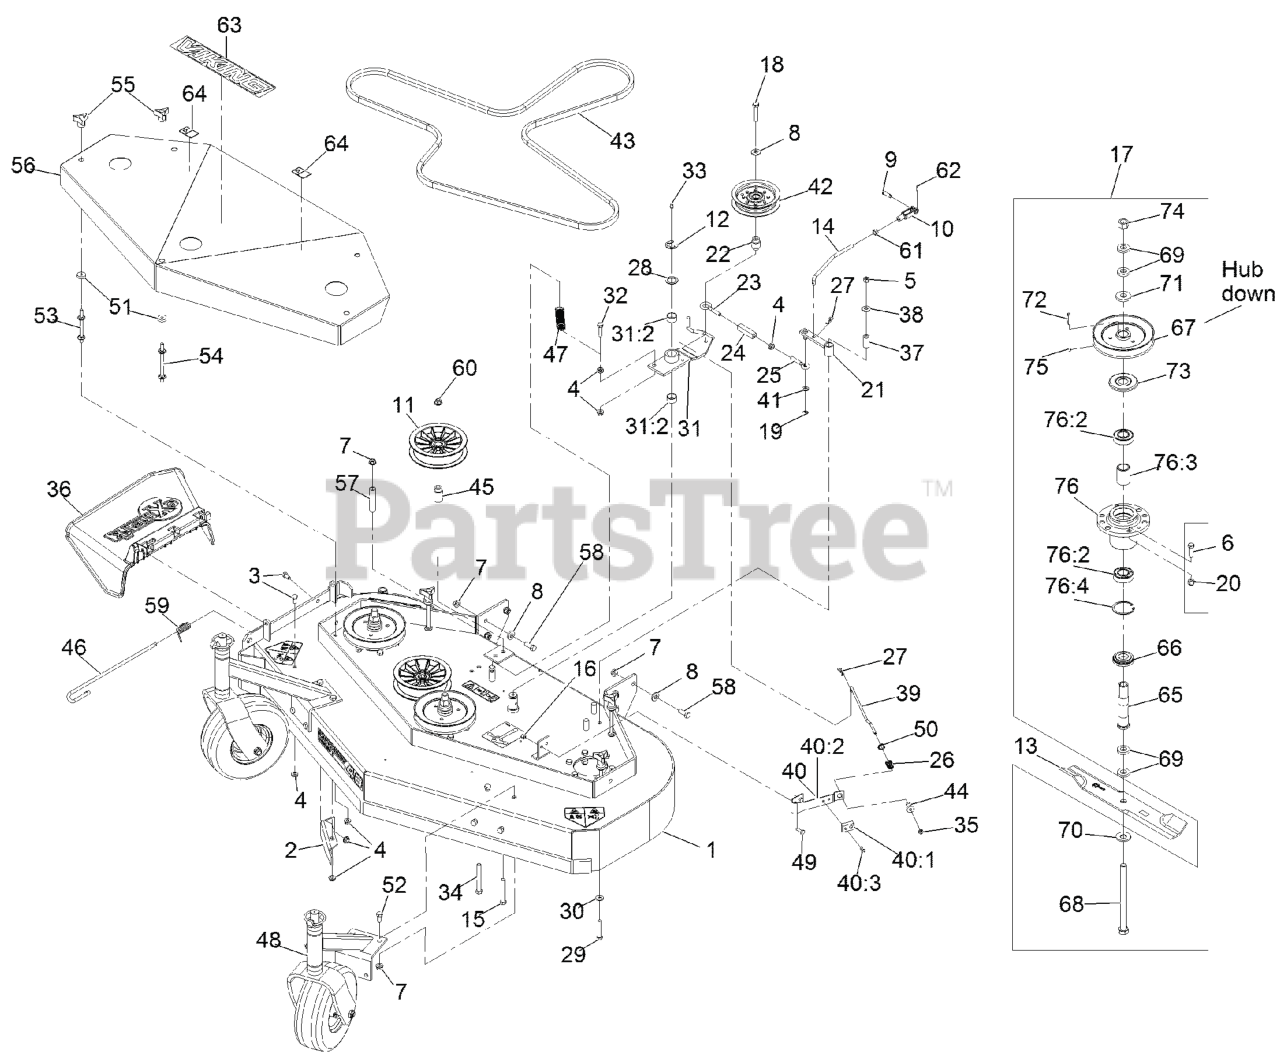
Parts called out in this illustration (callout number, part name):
1	DECK-SERVICE, 48
2	BAFFLE-DOGLEG
3	SCREW-HH
5	NUT-LOCK, NI
6	SCREW-HH
7	NUT-HHF, WHIZ
8	WASHER-BELLEVILLE
9	PIN-CLEVIS
10	YOKE-ADJUSTABLE
11	PULLEY,IDLER 5"
12	RING-RETAINING, EXT
14	ARM-LINKAGE, ASSIST
15	SCREW-HH
16	NUT-LOCK, NI
17	ASM, CUTTER HOUSING OUTER
18	SCREW-HH
19	RING-RETAINING, EXT
20	NUT-LOCK, NI
21	ARM-ASSIST, 32/36
22	BUSHING-ENGAGEMENT
23	EYEBOLT-THREAD, LH
24	BODY-TURNBUCKLE
25	EYEBOLT-THREAD, RH
26	SPRING-COMPRESSION
27	PIN-COTTER
28	WASHER-SPINDLE
29	SCREW-HH
30	WASHER-SPRING
31	IDLER ARM ASM
31:2	SLEEVE-BEARING
32	SCREW-HH, SPECIAL
33	FITTING-GREASE
34	SCREW-HH
35	NUT-LOCK, NI
36	CHUTE DEFLECTOR XRK M056
37	TUBE-PIVOT
38	WASHER-FLAT
39	ROD-BRAKE
40	PAD AND SPRING ASM
41	WASHER-PLAIN
43	BELT,BLADE 48
44	SPACER-FLANGED
45	BUSHING-IDLER
46	PIN-CHUTE
47	SPRING-EXTENSION
48	ASM-CASTER MNT W/WEIGHT
49	SCREW-HH
50	RING-PUSH ON
52	SCREW-HH
53	STUD-SHIELD, BELT (SHORT)
54	STUD-SHIELD, BELT (LONG)
55	KNOB-3 PRONG
56	Shield Weldmt, 48"
56	ASM,SHIELD W/DECALS 48 VI
58	SCREW-HH
59	SPRING, TORSION
60	NUT-HF, NI
61	NUT-HEX
62	PIN-COTTER
63	DECAL, VIKING HYDRO MODEL
64	DECAL-WARNING
65	TUBE-SPINDLE, SHORT
66	SPACER-GUARD, BOTTOM
67	SHEAVE
68	SCREW-CAP, HH
70	WASHER-SPRING
71	WASHER-RETAINER, SHEAVE
73	GUARD-BEARING, TOP
74	NUT-HEX
75	SETSCREW
76	Cutter Housing ASM
76	KIT, CUTTER HOUSING
76:2	BEARING-JACKSHAFT
76:3	SPACER-BEARING
76:4	RING-SNAP
